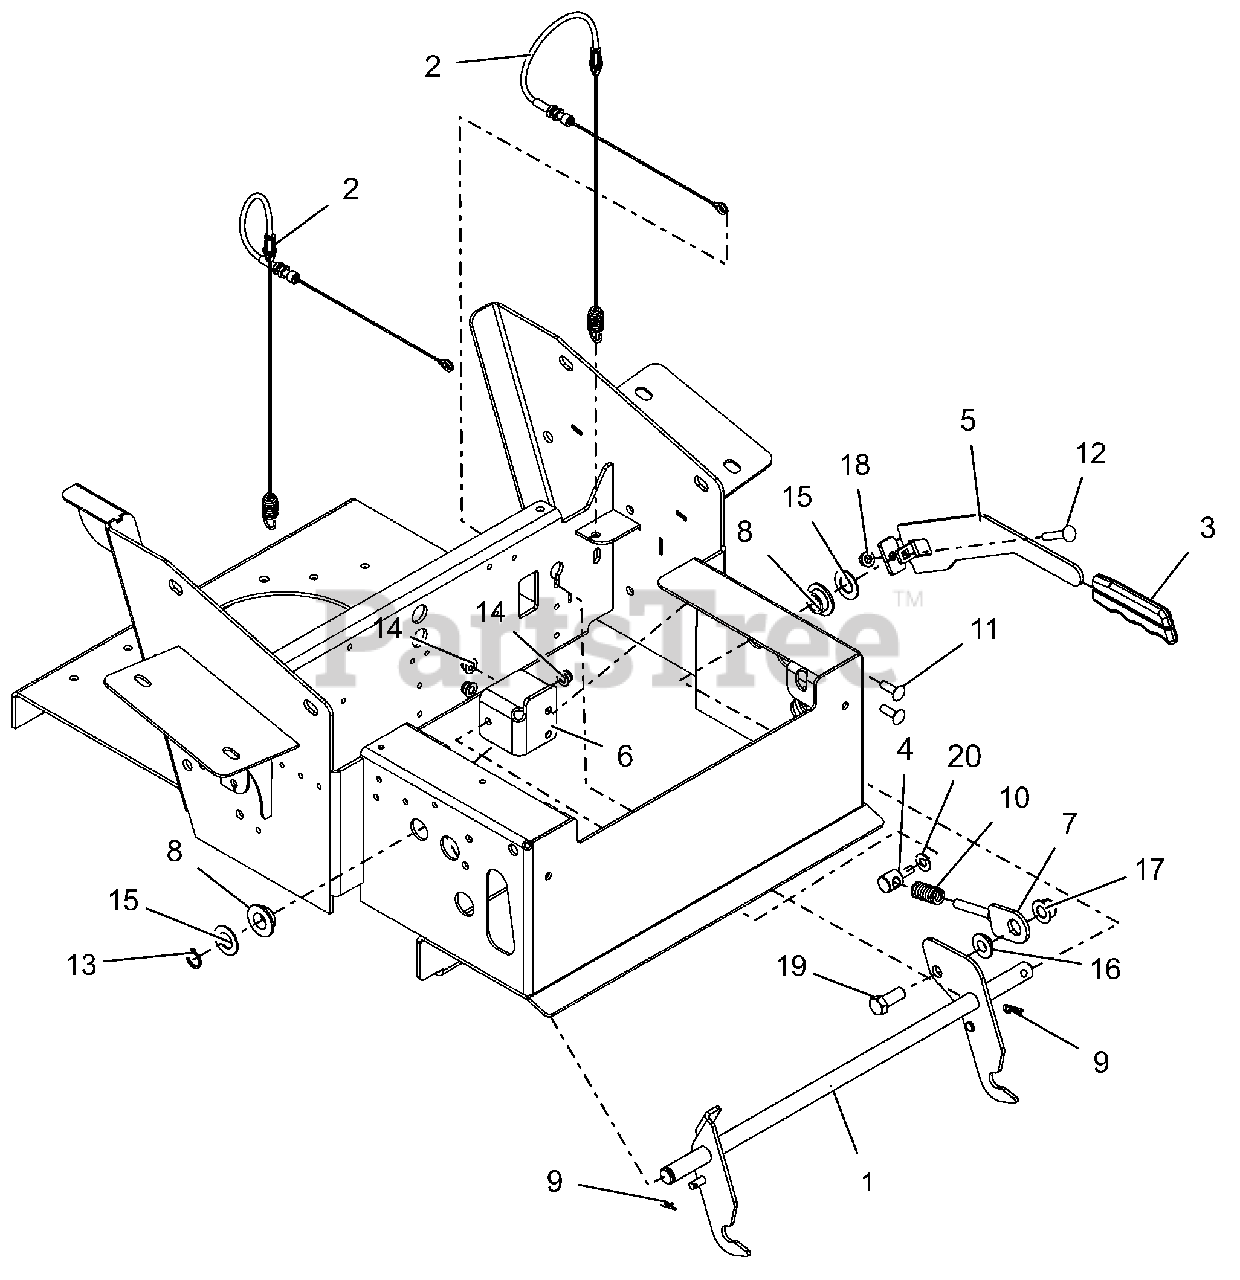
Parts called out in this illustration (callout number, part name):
1	PT/PT100 BRAKE LEVER WMT-LOW F
2	CABLE, BRAKE ACCUATING
3	GRIP, PARKING BRAKE (YELLOW)
4	.38-16 TRUNNION - LOW FILM
5	PT/PT100 BRAKE HANDLE - BLK
6	TRUNNION MTG BRACKET - BLACK
7	WLDMT, BRAKE SPRING MOUNTING
8	BSHG-FLG .762X1.48X.44 NYL
9	PIN-HAIR INT .08X.18X1.18 YWZC
10	SG-COMP .142 X .710 X 1.75
11	@BLT-RDHDSQNK .31-18X1.00 G5YZ
12	@BLT-RDHDSQNK .31-18X1.75 G5YZ
13	RG-RTNG-EXT .689X.078
14	@NUT-LK-NYL-FLG .31-18 YWZC
15	WSHR-FL-STL.755X1.375X.062YWZC
16	BSHG-FLG .515X.750X.310X1.120
17	@NUT-LK-NYL-FLG .50-13 YWZC
18	@NUT-LK-CTR-FLG .31-18 YZ GR F
19	@BLT-HEX .50-13X1.25 GR5 YWZC
20	@WSHR-FL-STL.406X.812X.065 YWZ
